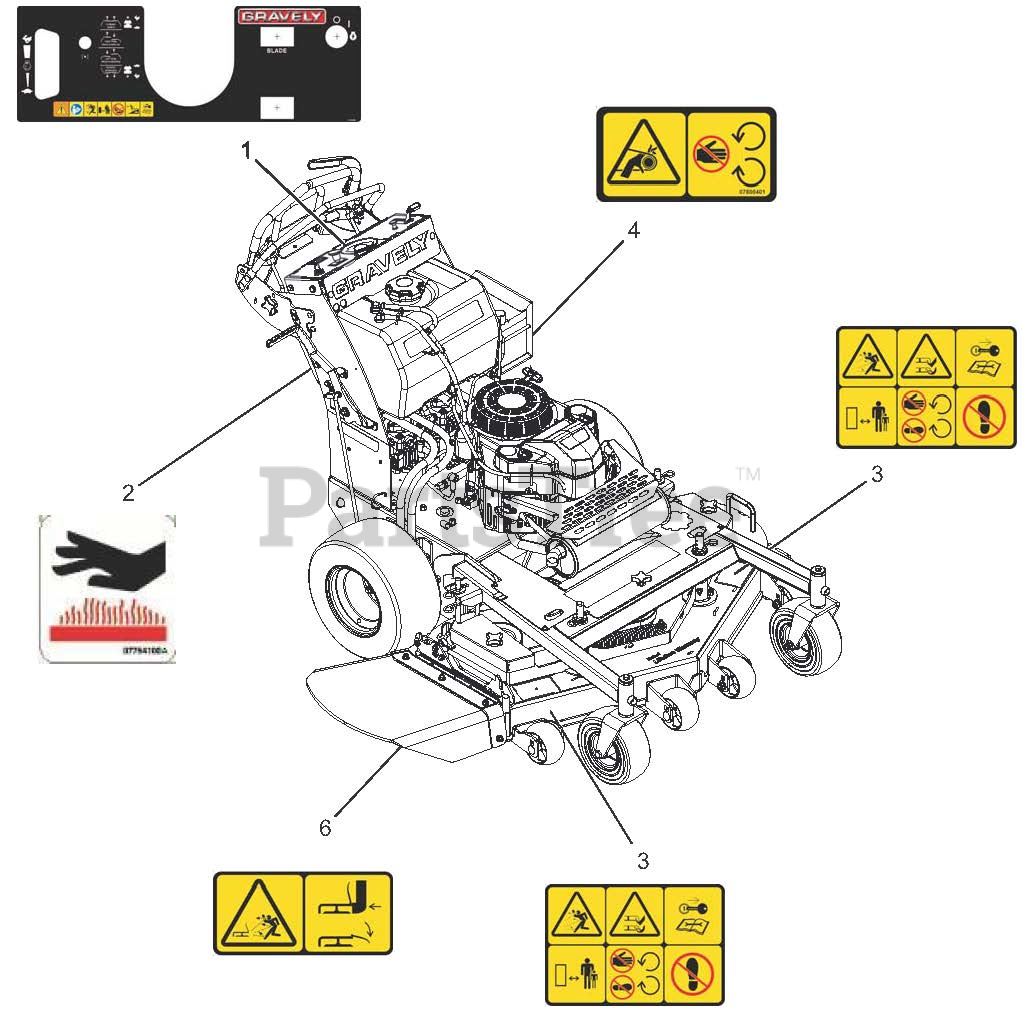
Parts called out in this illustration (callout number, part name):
1	DECAL, CONSOLE PS GRV MY13
2	DECAL HOT SURFACE
3	DECAL, SAETY - MOWER DECK
4	DECAL, SAFETY - GUARDING
6	DECAL, SAFETY - DECK GUARDING
